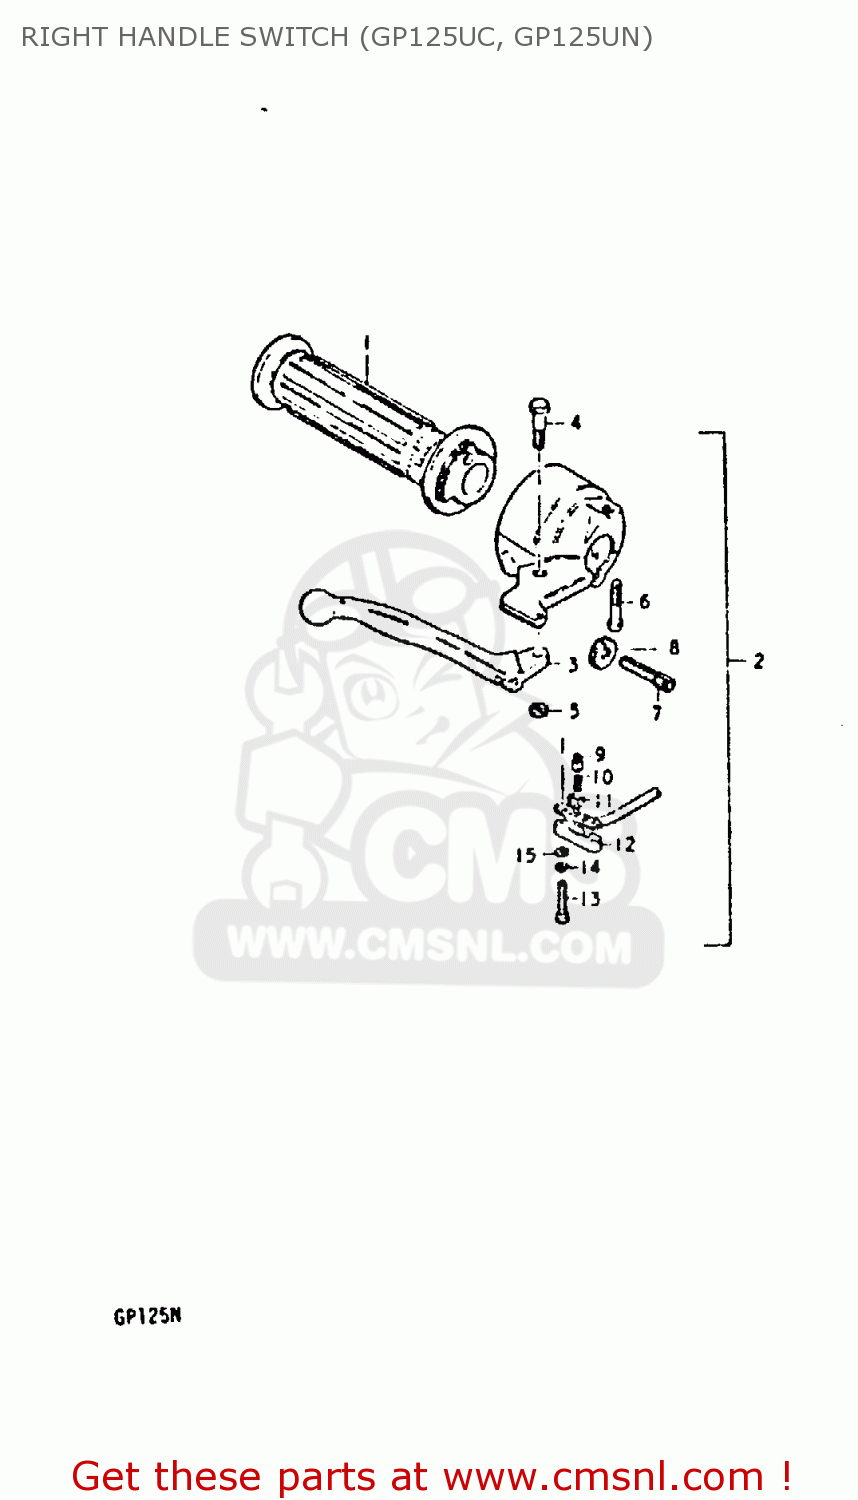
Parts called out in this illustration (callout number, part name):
1	GRIP,THROTTLE
2	BRAKE LEVER & SWITCH ASSY
3	LEVER,BRAKE
4	BOLT
5	NUT
6	SCREW
7	ADJUSTER,CABLE
8	NUT,CABLE ADJUSTER
9	HOLDER
10	SPRING
11	PLATE
12	COVER,FR BK TERMINAL BASE
13	SCREW
14	LOCK WASHER
15	WASHER
